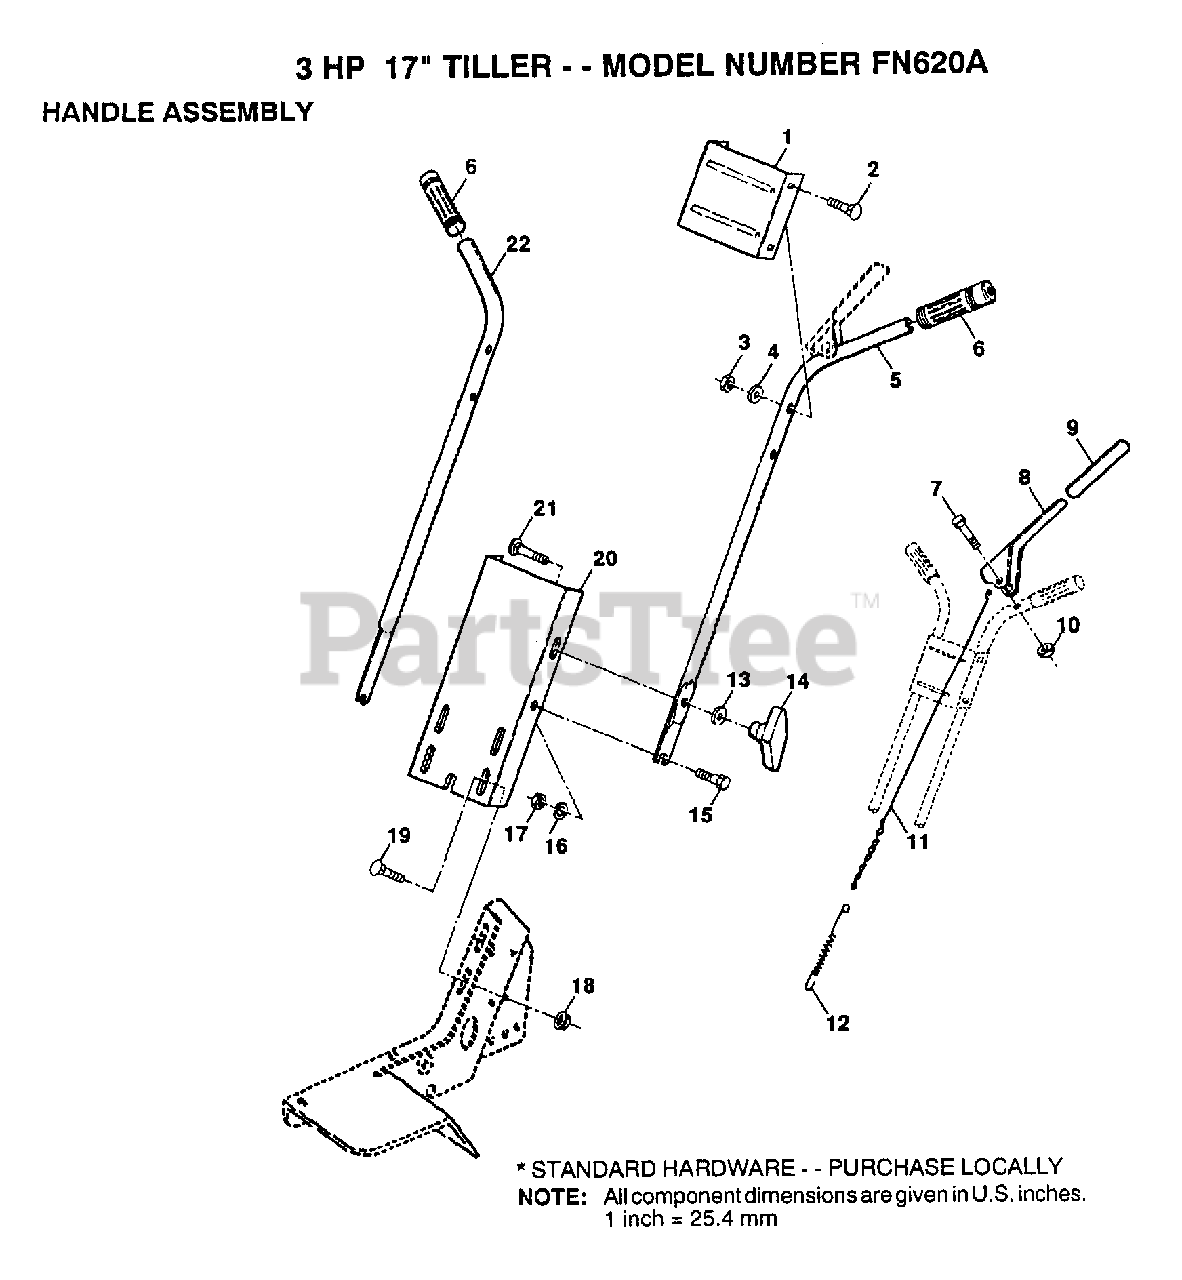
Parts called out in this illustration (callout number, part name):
1	HANDLE BRKT
2	BOLT
4	WASHER
7	BOLT.HEX.5/16-1.5
9	GRIP T
12	SPRING EXT TI
13	WASHER
16	LOCKWASHER
17	NUT.HEX.5/16-18
18	NUT
19	BOLT
20	PANEL. HANDLE
21	BOLT
